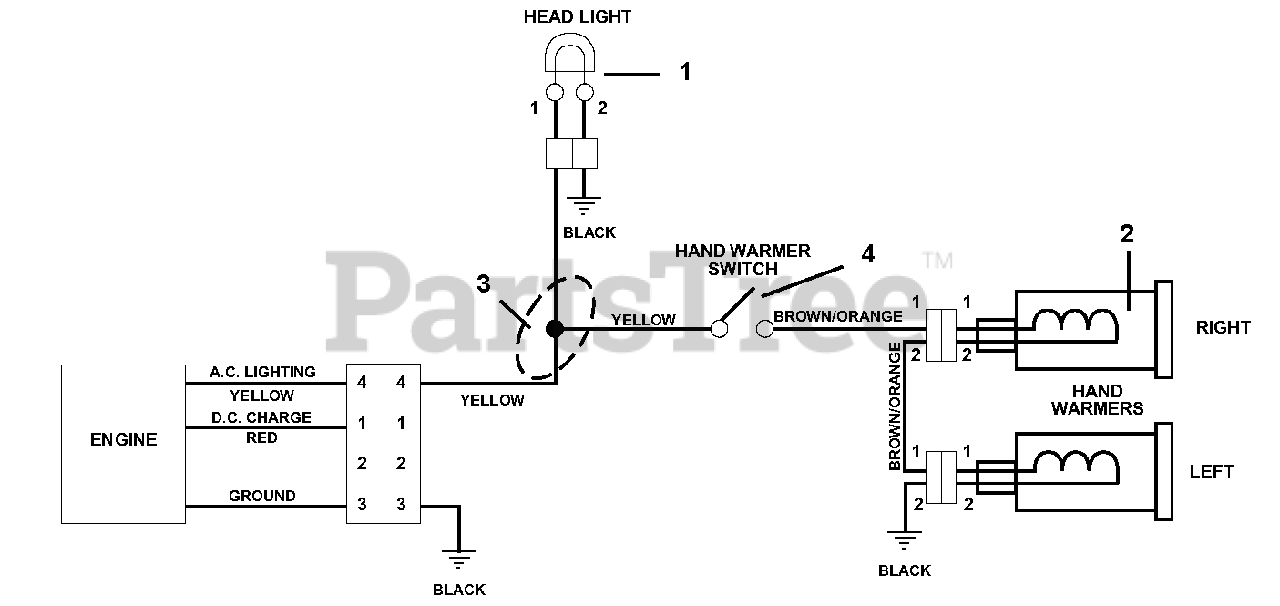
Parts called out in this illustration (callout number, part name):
1	Light, Halogen Assembly
2	Warmer, Hand with Terminal (Recommend Fast Drying Epoxy for Installation)
3	Wire Harness-Hand Warmer and Light
4	Switch, On/Off Hand Warmer
